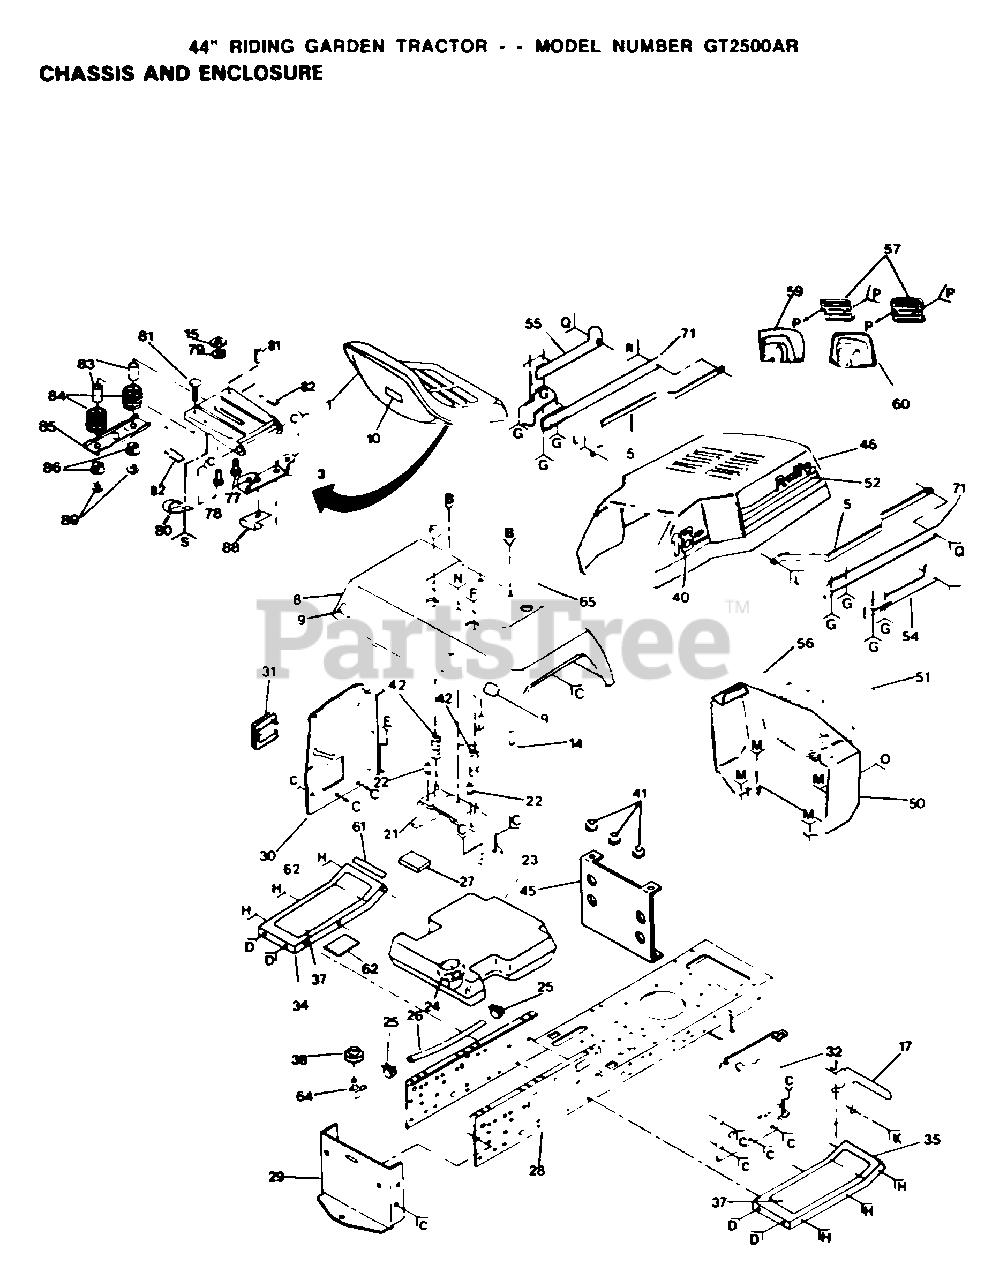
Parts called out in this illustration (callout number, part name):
9	REFLECTOR-TAIL YT
15	WASHER
17	GUARD MUFFLER HYT
22	NUT-PUSH YT
27	PAD-SPACER LT
28	CHASSIS ASSY
31	COVER ACCESS
32	PANEL DASH RH YT
34	FOOTREST - L.H.
35	FOOTREST - R.H.
37	PAD FOOTREST T
38	BUSHING OUTLET T
41	SNAP BUSHING T
54	STRAP ASSY T
55	STRAP ASSY T
56	SCREEN GRILL GTV
64	FUEL TANK STEM GT
71	STRAP ASSY-REAR T
78	BOLT
79	LOCKWASHER
80	CLIP T
81	BOLT
82	STRIP FORM
83	SPACER SPLIT
84	SPRING
85	BRKT SWITCH
89	NUT T
